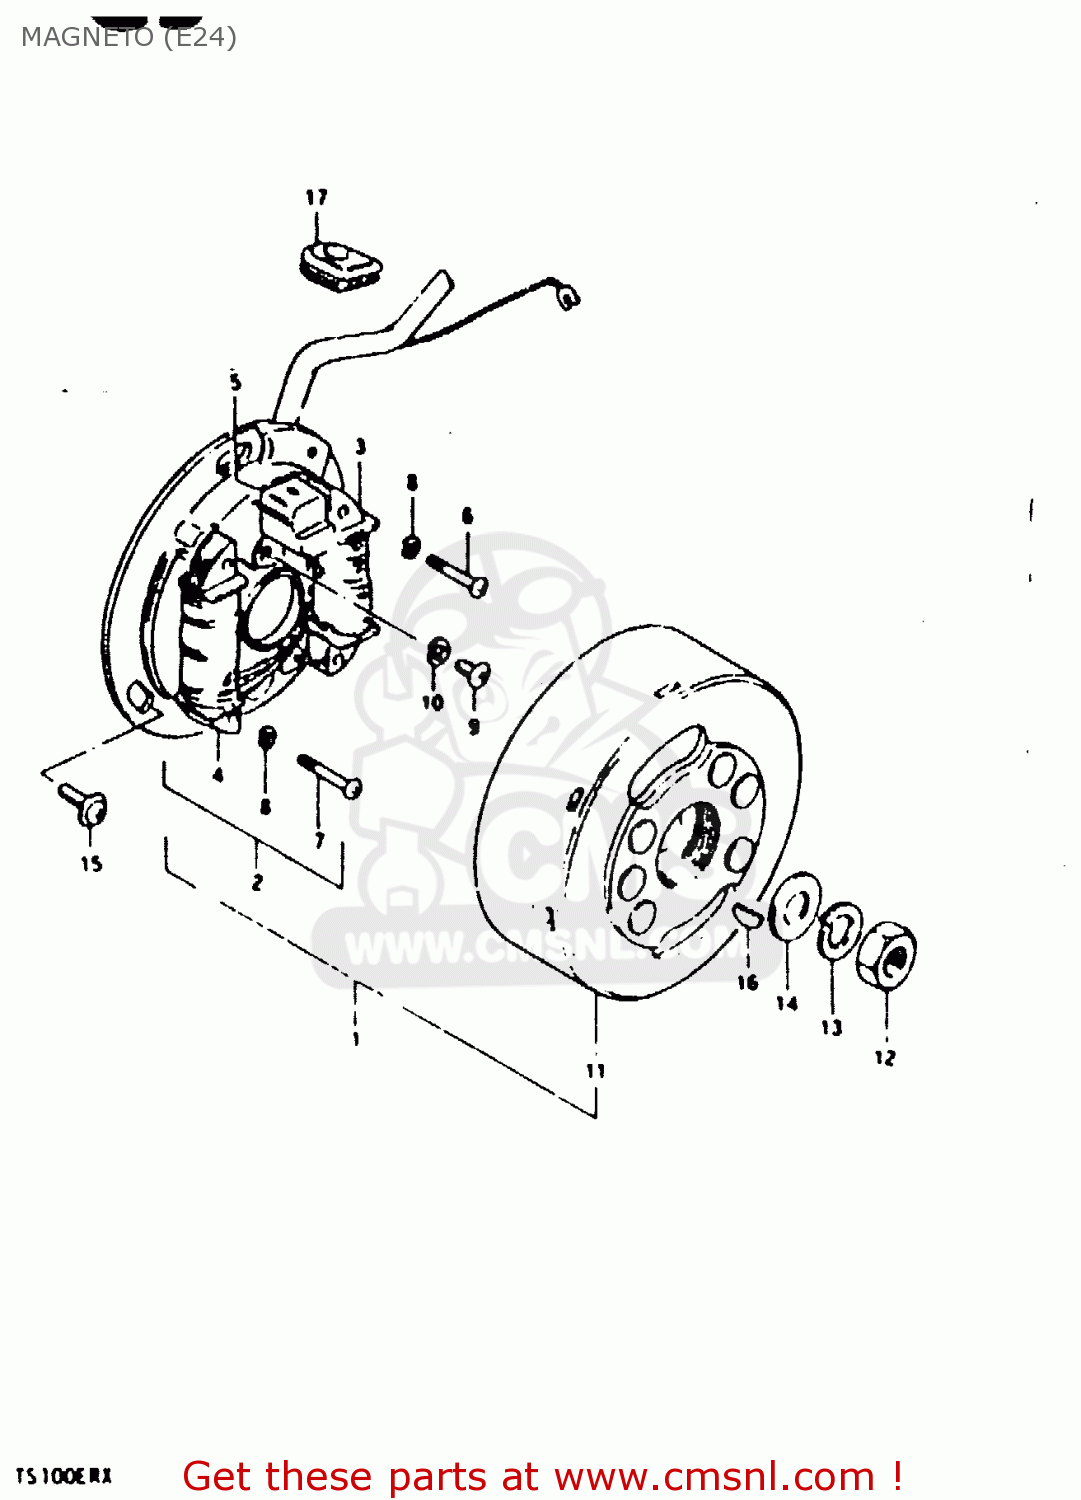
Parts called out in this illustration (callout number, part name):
1	MAGNETO ASSY
2	STATOR ASSY
3	COIL, LIGHTING
4	COIL
5	COIL,PULSER
6	SCREW 4X25
7	SCREW
8	LOCK WASHER
9	SCREW
10	LOCK WASHER
11	ROTOR
12	NUT (10MM)
13	LOCK WASHER
14	WASHER
15	SCREW
16	KEY
17	GROMMET
